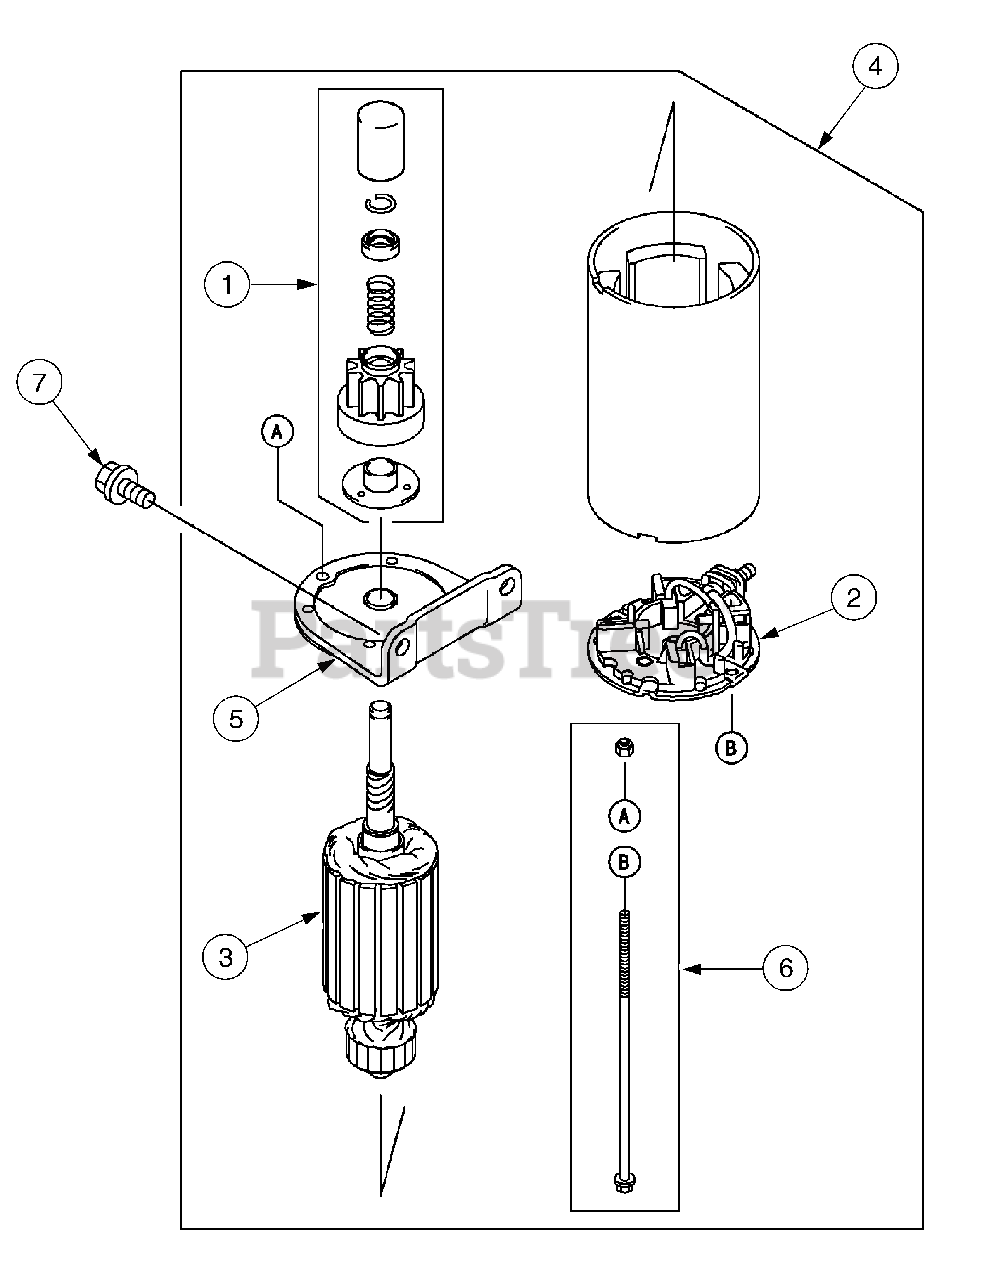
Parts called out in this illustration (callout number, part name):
1	Gear Assembly
2	Brush
4	Starter Assembly
5	Bracket
7	Bolt, Flanged
